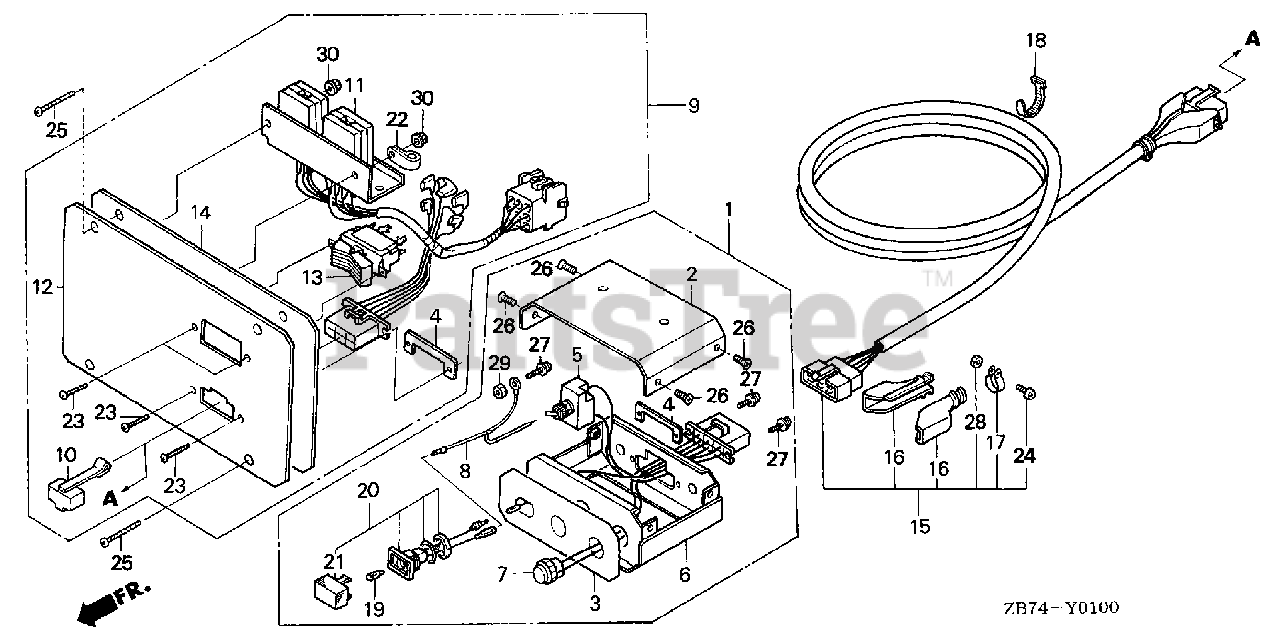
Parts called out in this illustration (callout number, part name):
1	BOX ASSY., SWITCH *R280*
2	COVER (UPPER) *R8*
3	PLATE, SWITCH & INDICATOR
4	PLATE, CONNECTOR SETTING
5	SWITCH, TOGGLE
6	CASE, SWITCH *R8* (BRIGHT RED)
7	SWITCH, PUSH
8	WIRE, GROUND
9	CONTROL ASSY., REMOTE
10	COVER, REMOTE CONTROL CONNECTOR
11	RELAY ASSY.
12	MARK, REMOTE CONTROL
13	SWITCH ASSY.
14	PANEL, RELAY
15	CABLE, REMOTE CONTROL (10M)
16	COVER, CONNECTOR
18	BAND B1, WIRE
19	BULB, WEDGE BASE (12V/2W)
20	SOCKET ASSY., LAMP (GREEN)
21	LENS (GREEN)
22	CLIP (9MM)
23	SCREW, PAN (3X8)
24	SCREW, PAN (3X12)
25	SCREW, PAN (5X10)
26	SCREW, FLAT (4X8)
27	SCREW-WASHER (4X12)
28	NUT, HEX. (3MM)
29	NUT, HEX. (4MM)
30	NUT, FLANGE (4MM)
